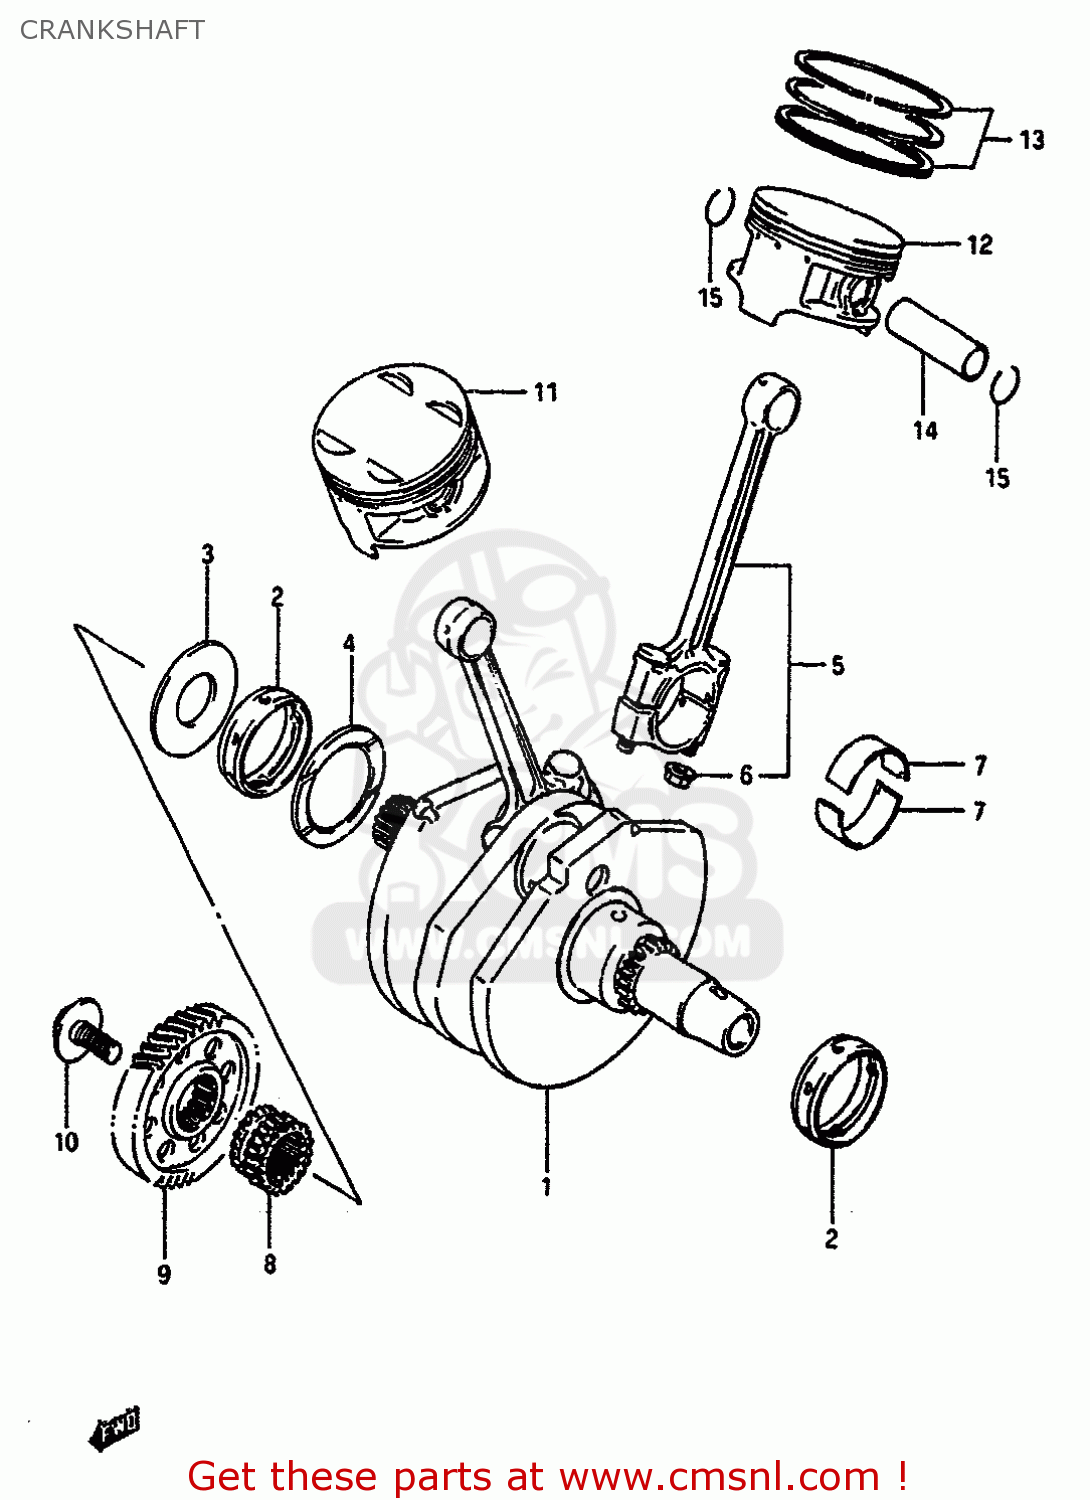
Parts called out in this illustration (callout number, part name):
1	CRANKSHAFT
2	METAL,CRANKSHAFT
3	WASHER,CRANK THRUST
4	WASHER(48.1X64X1.94)
5	CONNECTING ROD ASSEMBLY
6	NUT
7	BEARING,CRANK PIN
8	SPROCKET,CAM CHAIN DRIVE,R
9	GEAR,PRIMARY DRIVE
10	BOLT(12X28)
11	PISTON
12	PISTON
13	RING SET,PISTON
14	PIN,PISTON
15	CIRCLIP,PISTON PIN
